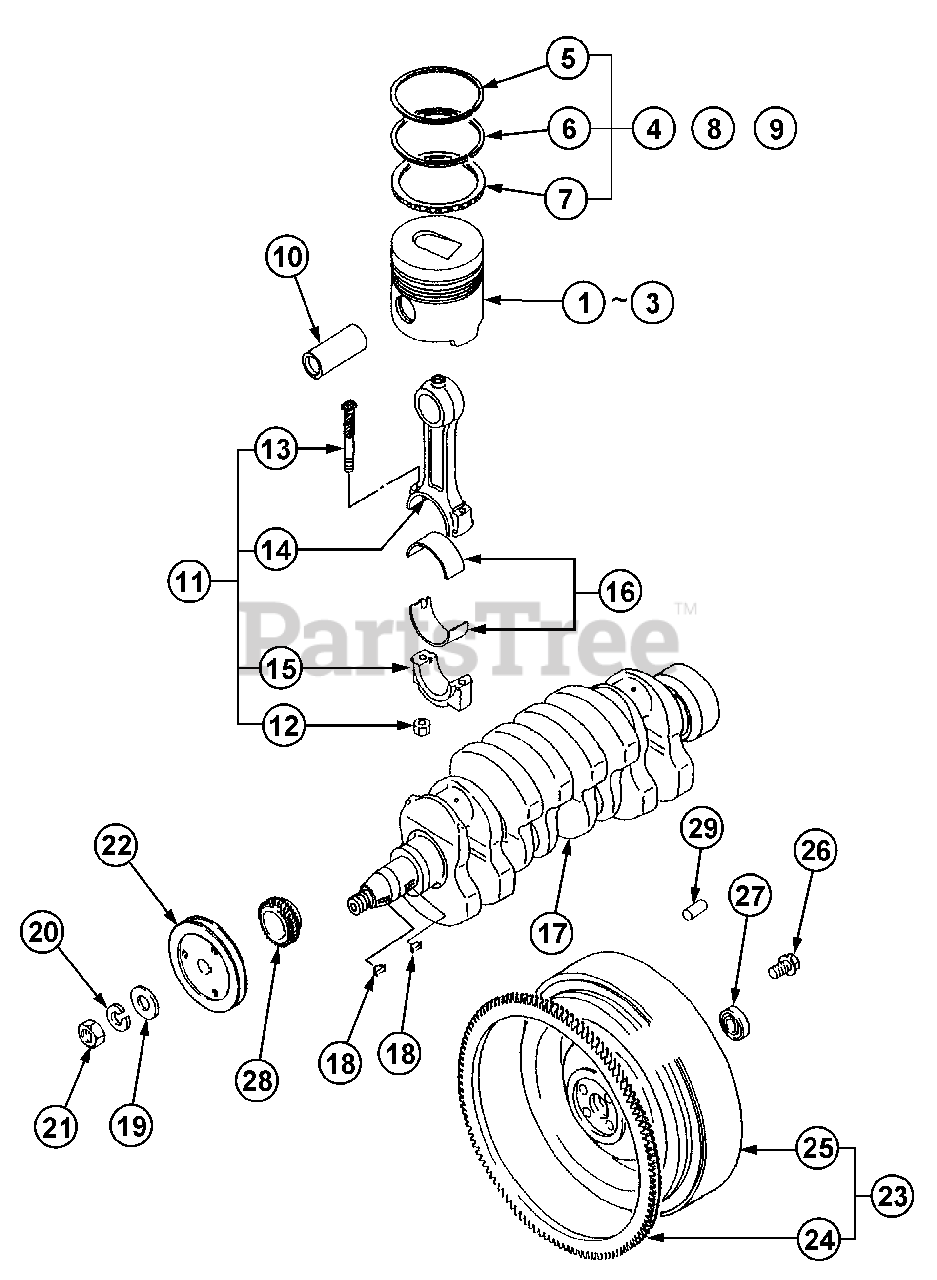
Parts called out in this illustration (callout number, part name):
2	Piston (O.S. 0.25)
3	Piston (O.S. 0.50)
4	Ring Seat, Piston (Std)
5	Ring, Piston
6	Ring, Piston
7	Ring
8	Ring Set, Piston (O.S. 0.25)
9	Ring Set, Piston (O.S. 0.50)
10	Pin, Piston
11	Con Rod Assy
12	Nut, Con Rod
13	Bolt, Con Rod
14	Connecting Rod
15	Cap, Con Rod
16	Metal Set, Con (STD)
18	Key, Woodruff
19	Washer, Plain
20	Washer, Spring
22	Pulley, Crankshaft
25	Flywheel
26	Bolt
27	Bearing, Ball
28	Gear, Crankshaft
